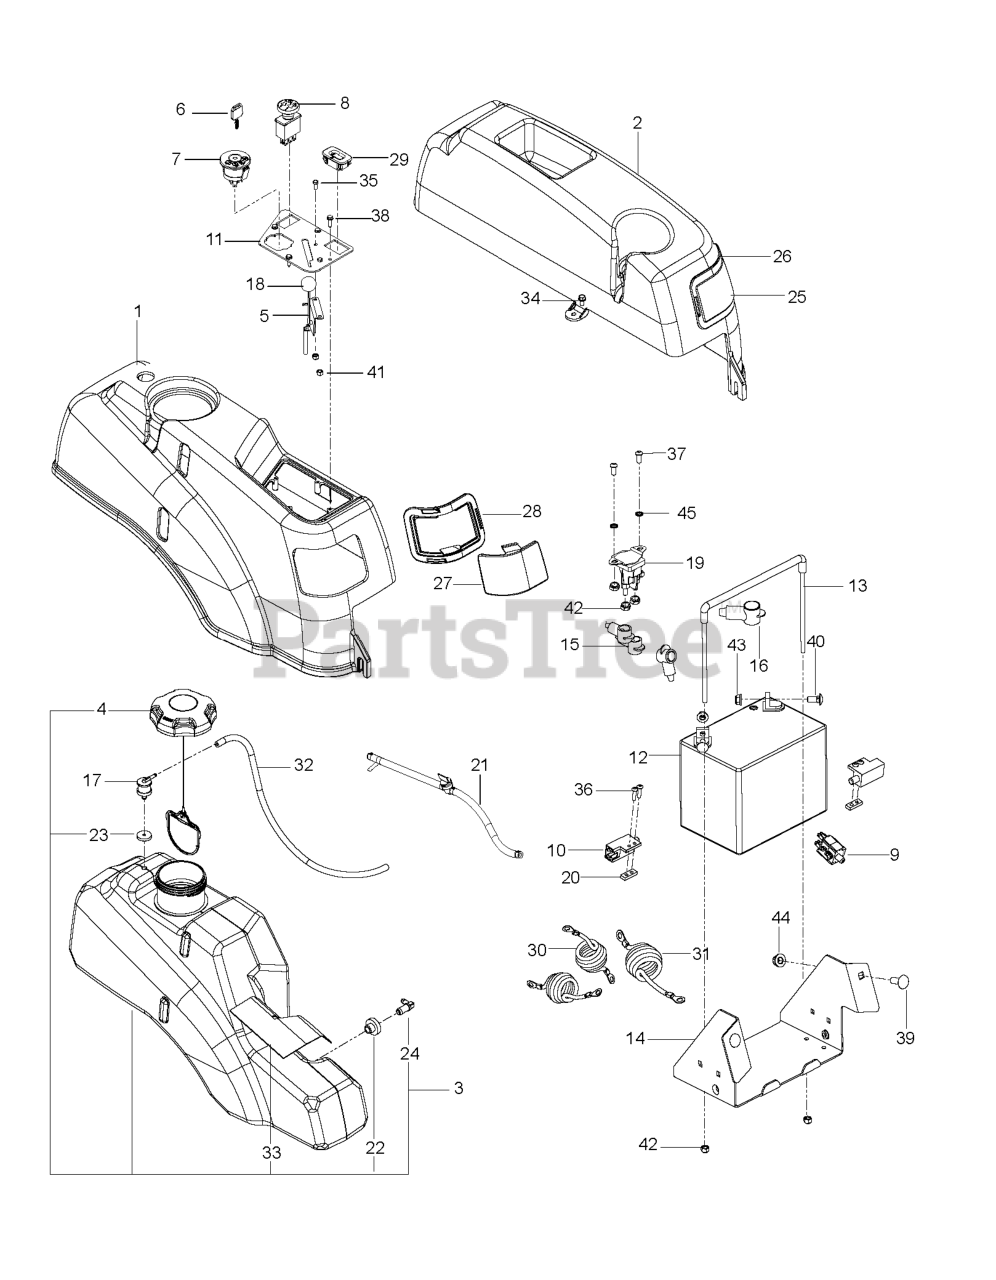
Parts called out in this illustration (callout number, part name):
1	FENDER, RT, GRAY
2	FENDER, LT, BLK
3	FUEL LINE ASSY
4	CAP, FUEL
5	CABLE, THROTTLE
6	KEY
7	RP IGNITION SWITCH
8	RP.SWITCH, BLADE
9	SWITCH, BRAKE 3P
10	SWITCH, INTERLOCK
11	PLATE.CONTROL.CONSOLE.BLACK
12	BATTERY, 12 V 330 AMP
13	BATTERY TIE DOWN ASSEMBLY
14	BOX, BATTERY, BLACK
15	TERMINAL COVER-SM
17	VALVE.FUEL.CHECK
18	KNOB.ROUND.BALL.BLACK
20	TAPPED PLATE
21	FUEL LINE ASSY
22	RUBBER GROMMET
23	GROMMET, CHECK VALVE
24	STEM, FUEL TANK
25	LENS, COLORED LEFT
26	LEFT HEADLIGHT RIM GREY
27	LENS, COLORED RIGHT
28	RT HEADLIGHT RIM GREY
29	HOUR METER
30	CABLE POSITIVE, LONG
31	BATTERY CABLE, NEGATIVE
32	HOSE, FUEL, 3/16" X 17-1/4"
33	SHIELD, HEAT
34	BOLT 1/4-20 X 1/2 HWST
35	HCS #10-24 X 1/2
36	SCREW #10 X 1/2 SELF TAPPING
37	SCR 1/4-20 X 5/8 BTN SKT HD ZD
38	SCR #10-12X3/4 HEX WAS HD ZD
39	RHSNB 3/8C X 1
40	BOLT 5/16C X 3/4" CARRIAGE
41	NUT 10-24 NYLOC
42	NUT.1/4-20.HEX.NYLOC.ZD
43	5/16-18 NYLOC FLANGE NUT
44	NUT 3/8-16 HEX FLG NYLOC ZD
45	WASHER 1/4 INT TOOTH
